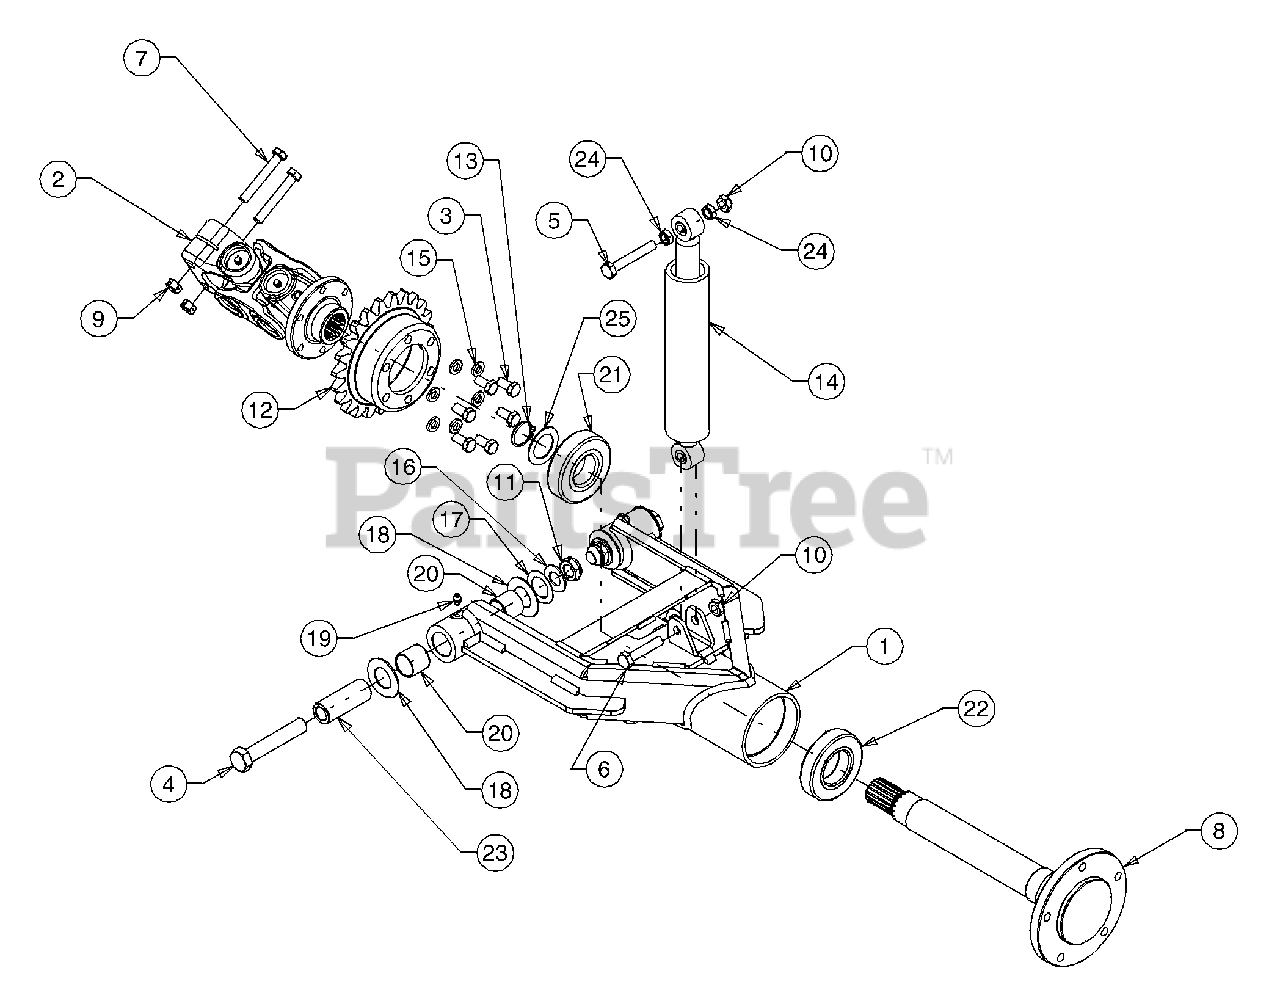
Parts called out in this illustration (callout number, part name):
2	Weld Coupling Assembly
3	Screw, Hex, 3/8-16 x .75, Gr5
4	Screw, Hex, 5/8-18 x 3.5, Gr5
5	Screw, M10-1.25 x .65, Gr8
6	Screw, M10-1.25 x .50, Gr8
7	Screw, Hex, 3/8-16 x 2.5, Gr5
8	Axle Shaft, Drive Center
9	Nut, Hex Lock, 3/8-16
10	Nut, Nylon Lock, M10-1.25
11	Nut, Jam Lock, 5/8-18, Gr5
12	Sprocket, Hub, 1.75 - 23T
13	Retaining Ring, External, 1.14
14	Shock Absorber, 2.88 Stroke
15	Washer, Lock, 3/8 , Regular Duty
16	Washer, Flat, .65 x 1.25 x .075
17	Washer, Flat, 1.06 x 1.56 x .020
18	Washer, Flat, 1.010 x 1.86 x .060
19	Lube Fitting, 3/16
20	Bearing, 1.0 x 1.125 x 1.0
21	Ball Bearing, Internal Axle
22	Ball Bearing, External Axle
23	Spacer, .63 x 1.0 x 2.594
24	Spacer, Shock
25	Spacer, 1.78 x 1.88
